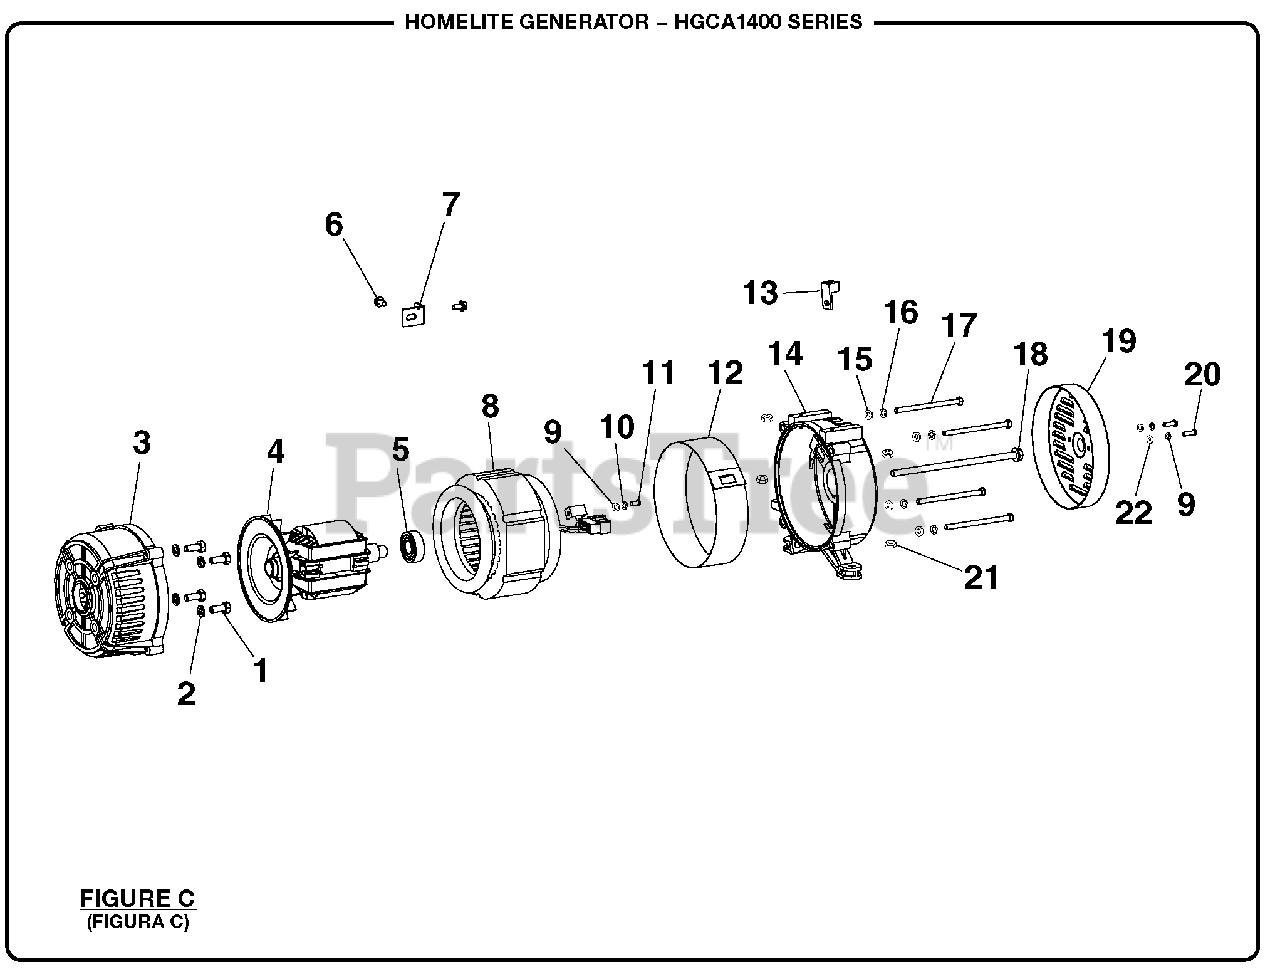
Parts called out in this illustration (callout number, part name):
2	Bolt (M6 x 25 mm)
3	Fuel Strainer
7	Fuel Filter
10	Lock Washer (M5)
11	Bolt (M5 x 10 mm)
13	Grounding Pin
14	Bearing Case
15	Washer (M6)
16	Lock Washer (M6)
19	Brush Cover
21	Lock Nut (M8)
22	Lock Washer (M5)
